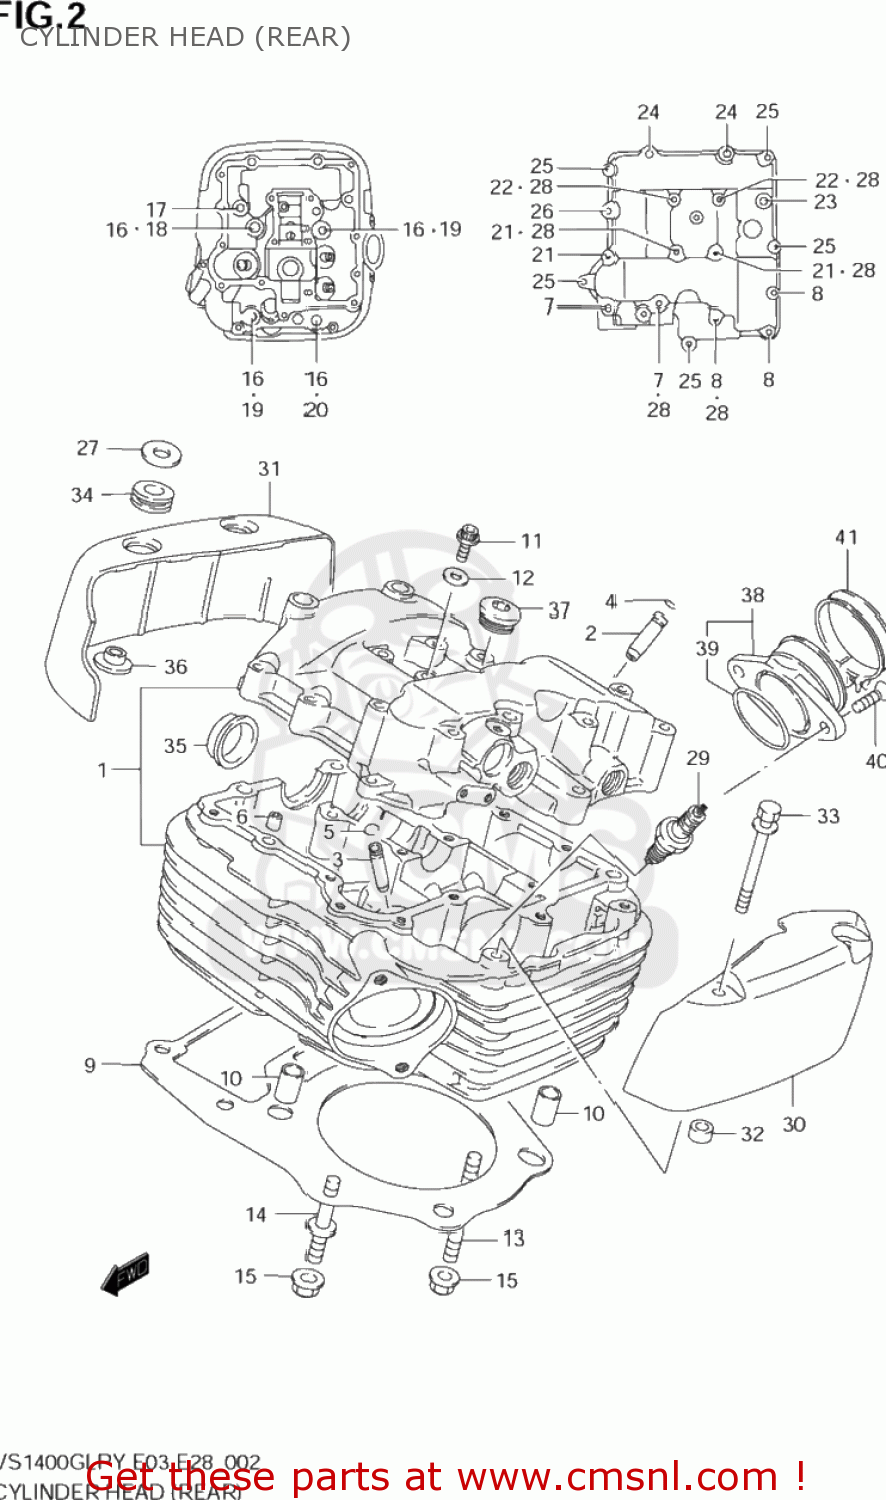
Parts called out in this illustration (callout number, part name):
1	HEAD ASSEMBLY,CYLINDER,REAR
2	GUIDE,INTAKE VALVE
3	GUIDE,INTAKE VALVE
4	RING,SNAP
5	RING,SNAP
6	PIN(6.2X8X11)
7	BOLT(6X60)
8	BOLT(6X55)
9	GASKET,CYLINDER HEAD RR (NAS)
10	PIN
11	BOLT
12	GASKET(6.2X13X1.2) (NAS)
13	BOLT,STUD
14	BOLT,STUD
15	NUT
16	WASHER(10.5X22X2.3)
17	BOLT(8X57)
18	BOLT(10X180)
19	BOLT(10X190)
20	BOLT(10X215)
21	BOLT(6X50)
22	BOLT(6X45)
23	BOLT(8X130)
24	BOLT(8X268)
25	BOLT
26	BOLT
27	WASHER(8.5X24X1.6)
28	GASKET(5.8X13X1.2) (NAS)
29	SPARK PLUG DP7EA-9
30	CAP,CYLINDER HEAD COVER RL
31	CAP,CYLINDER HEAD COVER RR
32	CUSHION,R CAP
33	BOLT
34	CUSHION
35	PLUG(OD:30)
36	BUSH
37	PLUG,22X11
38	PIPE ASSY,INTAKE RR
39	O RING(D:1.9,ID:40.7)
40	SCREW
41	CLAMP
